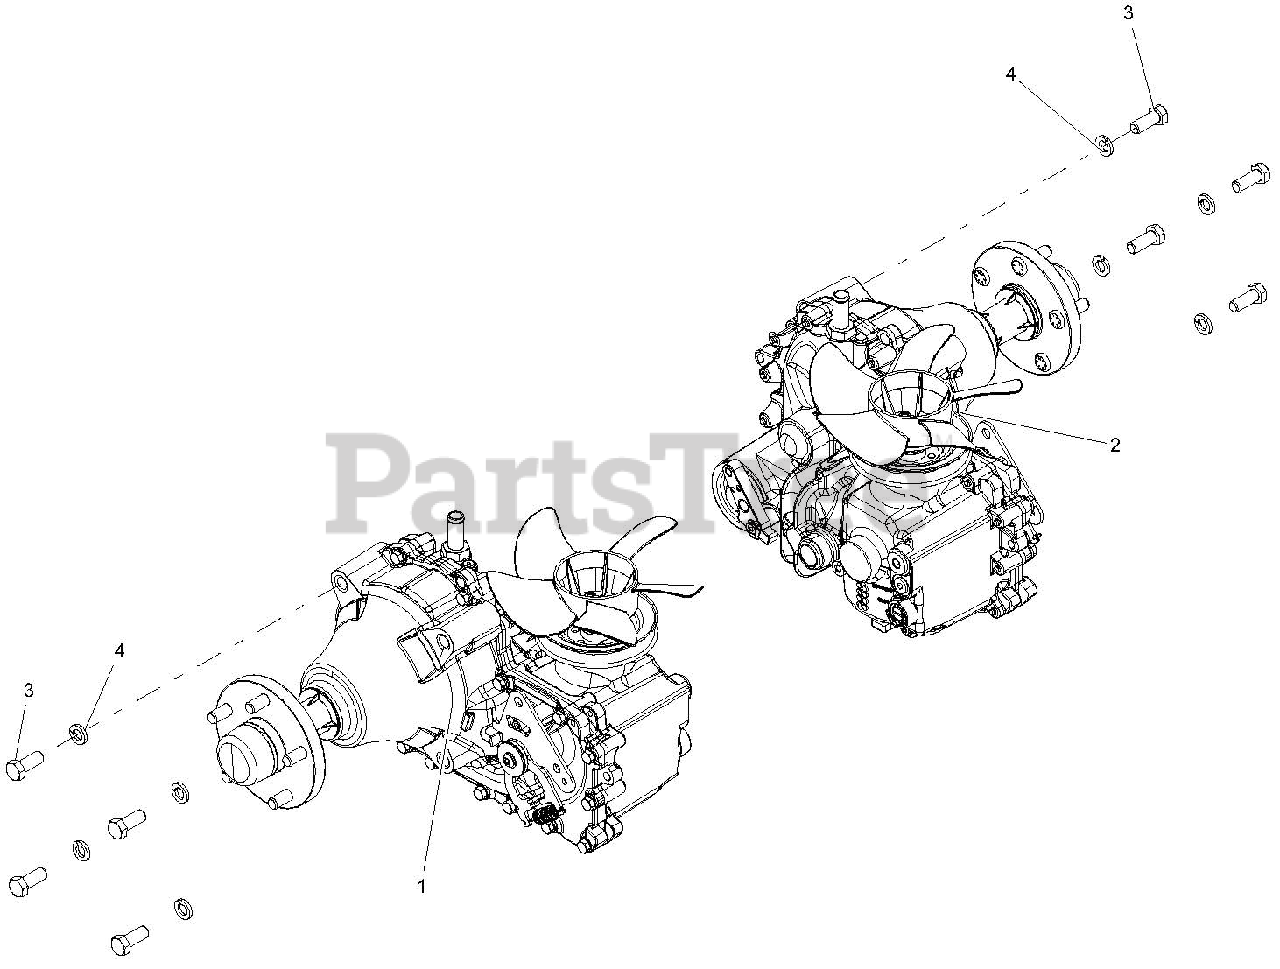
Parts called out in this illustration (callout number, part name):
1	TRANS, R.H. HG ZT-5400
2	TRANS, LH HG ZT-5400
3	BLT-HEX .50-13X1.25 GR5 YWZC
4	WSHR-LK .50X.125 REG YWZC
